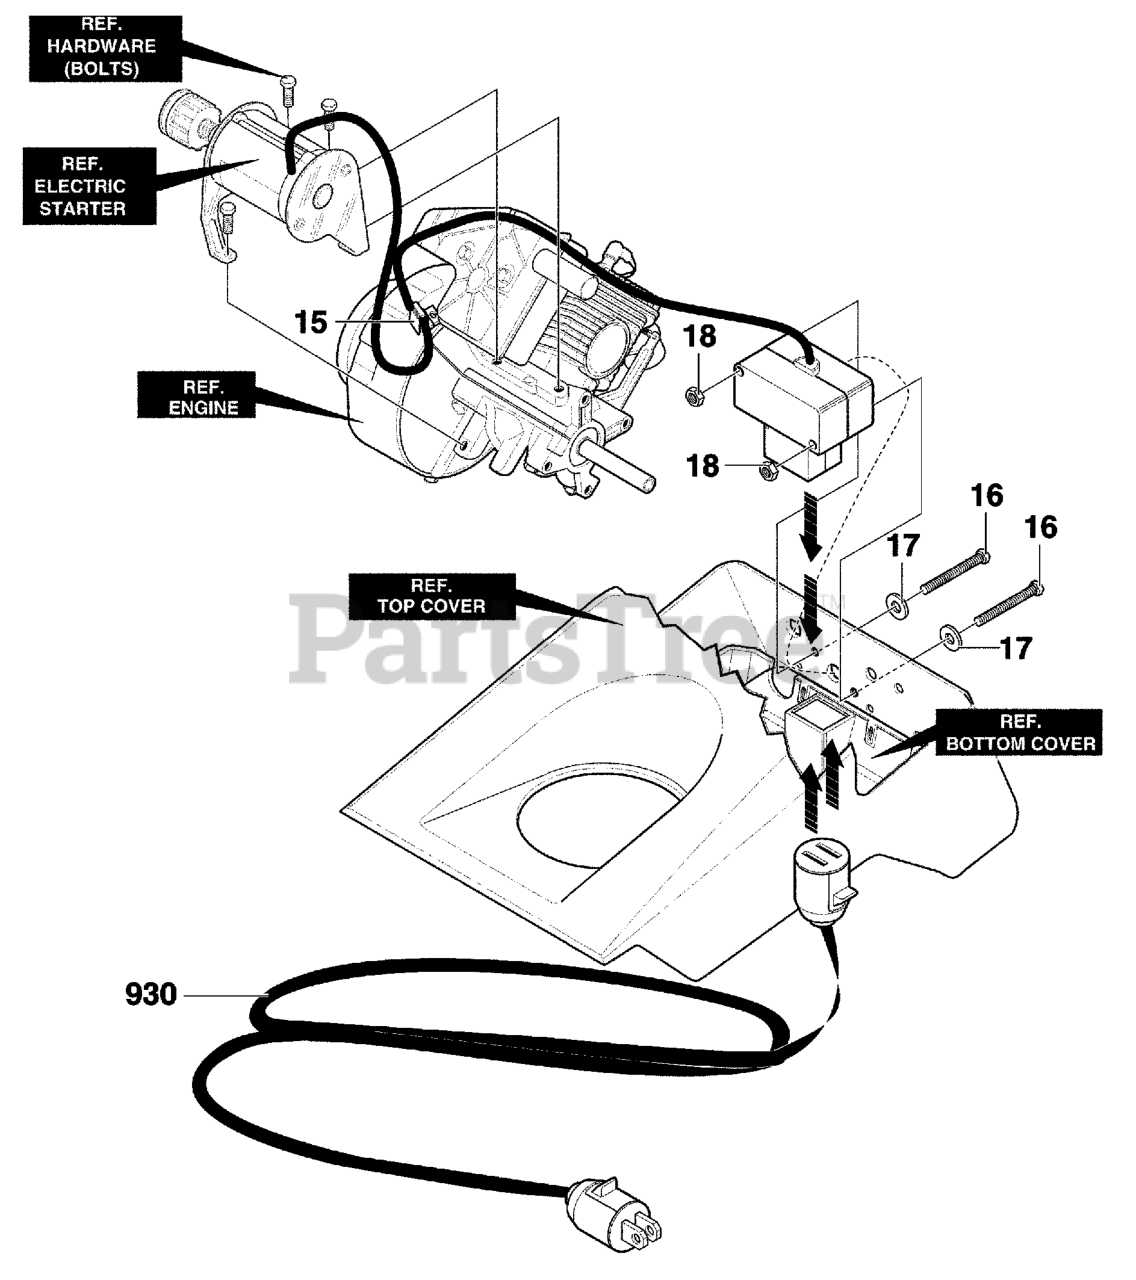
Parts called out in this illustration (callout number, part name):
15	RETAINER
16	SCREW #8-32X3.00
17	WASHER, FLAT .188X.38X.040
18	NUT, #8-32X3.00
930	CORD EXTENSION
